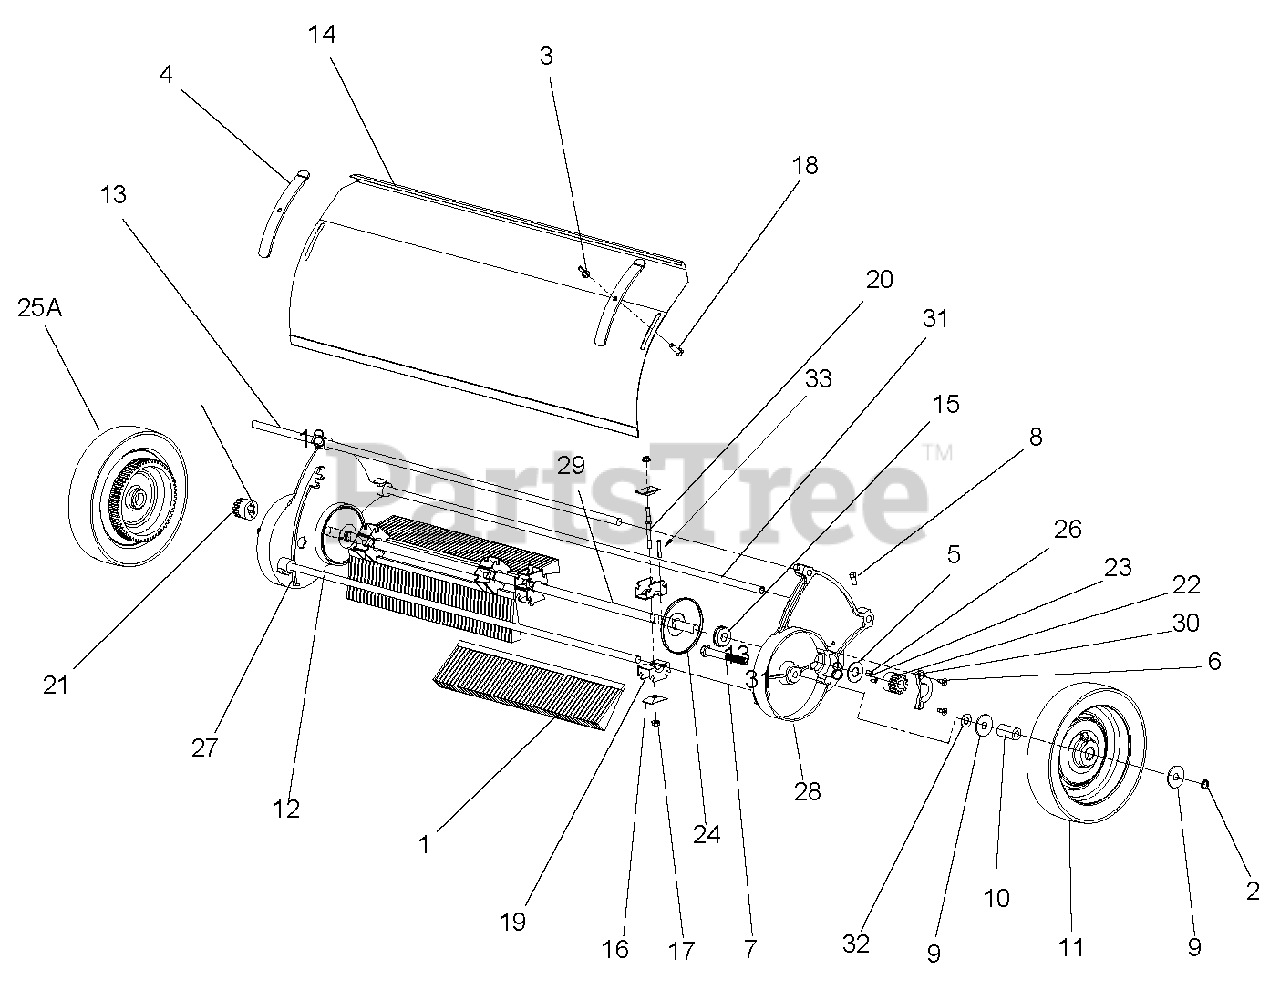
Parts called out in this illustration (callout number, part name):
1	Brush Assembly
1A	Brush Kit
2	Nut, 1/2-20 Hex Nyloc
3	Nut, 5/16-18 Wing
4	Clamp, Hood
5	Washer, .656 x 1.50 x .06 Flat
6	Screw, 1/4-20 x 5/8 Flat Hd.
7	Bolt, Axle
8	Set Screw, Square Hd.
9	Washer, 5.16 x 1.625 x .075 Flat
11	Wheel Hub
12	Tie Rod, Zinc Plated
13	Tie Rod
14	Hood, Parker Burgundy
15	Bearing, .625 x .150 Flange Radial
16	Clamp, Brush Strip
17	Nut, 1/4-20 Flanged
18	Bolt, 5/16-18 x 1 Hex 5
20	Stud, Plated Zinc
21	Pinion, Right
22	Pinion, Left
22A	Pinion Kit
23	Dowel Pin, .1875" OD x .4375"
24	Dust Cover, Zinc Plated
25	Tire Only
25A	Tire Assembly
26	Pawl Spring
27	Side Plate, Right
28	Side Plate, Left
29	Shaft, Reel
30	Casting, Cover Pinion
31	Adjust Tube, 1/2 x .065 Zinc Plated
32	Washer, .656 x 1.50 x .06 Fiber
33	Pin, Roll 3/16 x 1.0
